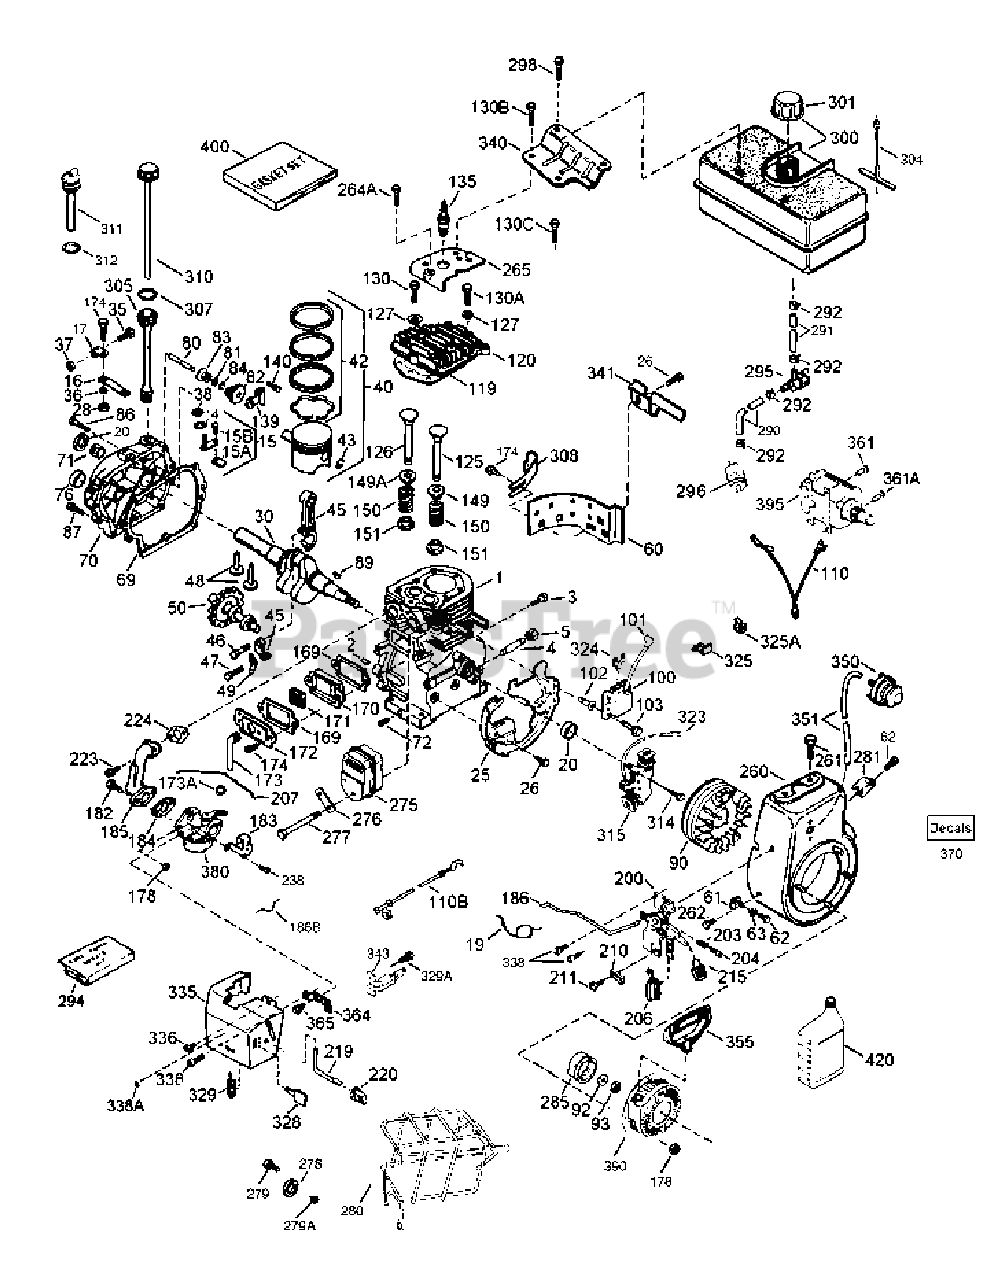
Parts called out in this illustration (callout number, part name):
1	Cylinder Cast Iron Liner 3-5/16 inch
2	Dowel Pin
3	Screw, 1/4-20 x 1/2"
4	Oil Drain Extension
5	Extension Cap, 1/4-18 NPT
14	Flat Washer
15	Governor Rod Incl. 15A & 15B
15A	Governor Yoke
15B	Screw, 6-40 x 5/16"
16	Governor Lever
17	Governor Lever Clamp
18	Screw, T-15, 8-32 x 7/16"
19	Speed Control Spring
25	Blower Housing Baffle
26	Screw 1/4-20 x 19/32"
28	Lock Nut, 8-32
30	Crankshaft
35	Screw, 10-32 x 3/4"
36	Lock Washer #8
37	Lock Nut, 10-32
38	Retaining Ring
40	Piston, Pin & Ring Set .010" OS Incl. 41, 42 & 43
40	Piston, Pin & Ring Set Std Incl. 41, 42 & 43
42	Ring Set .010" OS
42	Ring Set Std.3-5/16"
43	Piston Pin Retaining Ring
45	Connecting Rod Assembly Incl. 47 & 49
47	Connecting Rod Bolt 1/4-20 x 1-5/16"
48	Valve Lifter
49	Oil Dipper
50	Camshaft MCR
60	Blower Housing Extension
69	Cylinder Cover Gasket
70	Cylilnder Cover Incl. 71, 75, 80 thru 84
71	Crankshaft Bushing
80	Governor Shaft
82	Governor Gear Ass'y. Incl. 81
83	Governor Spool
84	Retaining Ring
86	Screw 1/4-20 x 1-3/16"
87	Screw, 1/4-20 x 1- 11/16"
89	Flywheel Key
90	Flywheel 3 Amp, w/ring gear
92	Belleville Washer
93	Flywheel Nut 5/8-18
100	Solid State Ignition Incl. 101
101	Spark Plug Cover
102	Solid State Mounting Stud
103	Screw, T-15, 10-24 x 15/16"
110	Ground Wire
119	Cylinder Head Gasket
120	Cylinder Head
125	Exhaust Valve 1/32" OS Incl. 151
125	Exhaust Valve Std.Incl. 151
126	Intake Valve Std. Incl. 151
127	Flat Washer
128	Belleville Washer
130	Screw, 5/16-18 x 1-7/16"
130A	Screw 5/16-18 x 2"
130C	Screw, 5/16-18 x 39/64"
135	Resistor Spark Plug RJ19LM
139	Governor Gear Bracket
140	Screw, 10-24 x 1/2"
149	Valve Spring Cap
149A	Intake Valve Seal
150	Valve Spring
151	Valve Spring Cap
169	Valve Cover Gasket
170	Breather Body
171	Breather Element
172	Valve Cover
173	Breather Tube
174	Screw, 10-24 x 1/2"
178	Nut & Lock Washer 1/4-28
200	Manual Control Bracket Incl. 203, 204 & 206
203	Compression Spring
204	Screw, T-10, 5-40 x 7/16"
211	Screw, 10-32 x 3/8"
215	Control Knob
220	Control Knob
260	Blower Housing
261	Screw, 5/16-18 x 3/4"
262	Screw, 5/16-18 x 9/16"
264A	Screw, 1/4-20 x 5/8"
265	Cylinder Head Cover
276	Locking Plate
277	Screw, 5/16-18 x 4-13/64"
285	Starter Cup
290	Fuel Line 32.0" length
292	Fuel Line Clamp
298	Screw, 1/4-15 x 3/4"
300	Fuel Tank Incl. 292 & 301 Black Ploy 1 Gal., 3.75 ltr.
301	Fuel Cap Red Plastic1-1/2" I.D.
305	Oil Fill Tube
308	Fill Tube Clip
314	Screw, 1/4-20 x 3/4"
315	Alternator Coil 18 Watt
325	Wire Clip
328	Ignition Key
329A	Screw, 8-32 x 23/64"
335	Carburetor Cover Incl. 328
336	Screw, 10-32 x 1/2"
338	Screw, 10-32 x 1/2"
340	Fuel Tank Bracket
341	Fuel Tank Bracket Lower
343	Key Switch Bracket Incl. 343A
350	Primer Assembly
351	Primer Line
355	Starter Handle Mitten Grip
361	Screw, T-30, 1/4-20 x 15/32"
361A	Screw, 6-32 x 2-1/2"
370	Warning Decal Bilingual
370	Decal - Speed Control & Choke
370	Decal - Primer -International Symbol
370	Decal - Tecumseh Logo for Top Recoil Starter
370	Warning Decal
380	Carburetor Incl. 184
390	Rewind Starter
400	Gasket Set Incl. Items marked *
420	SAE 5W30 4-Cycle Engine Oil Quart Winter
702	Screw, 5/16-18 x 1-25/32"
999	Winter Maintenance Kit
